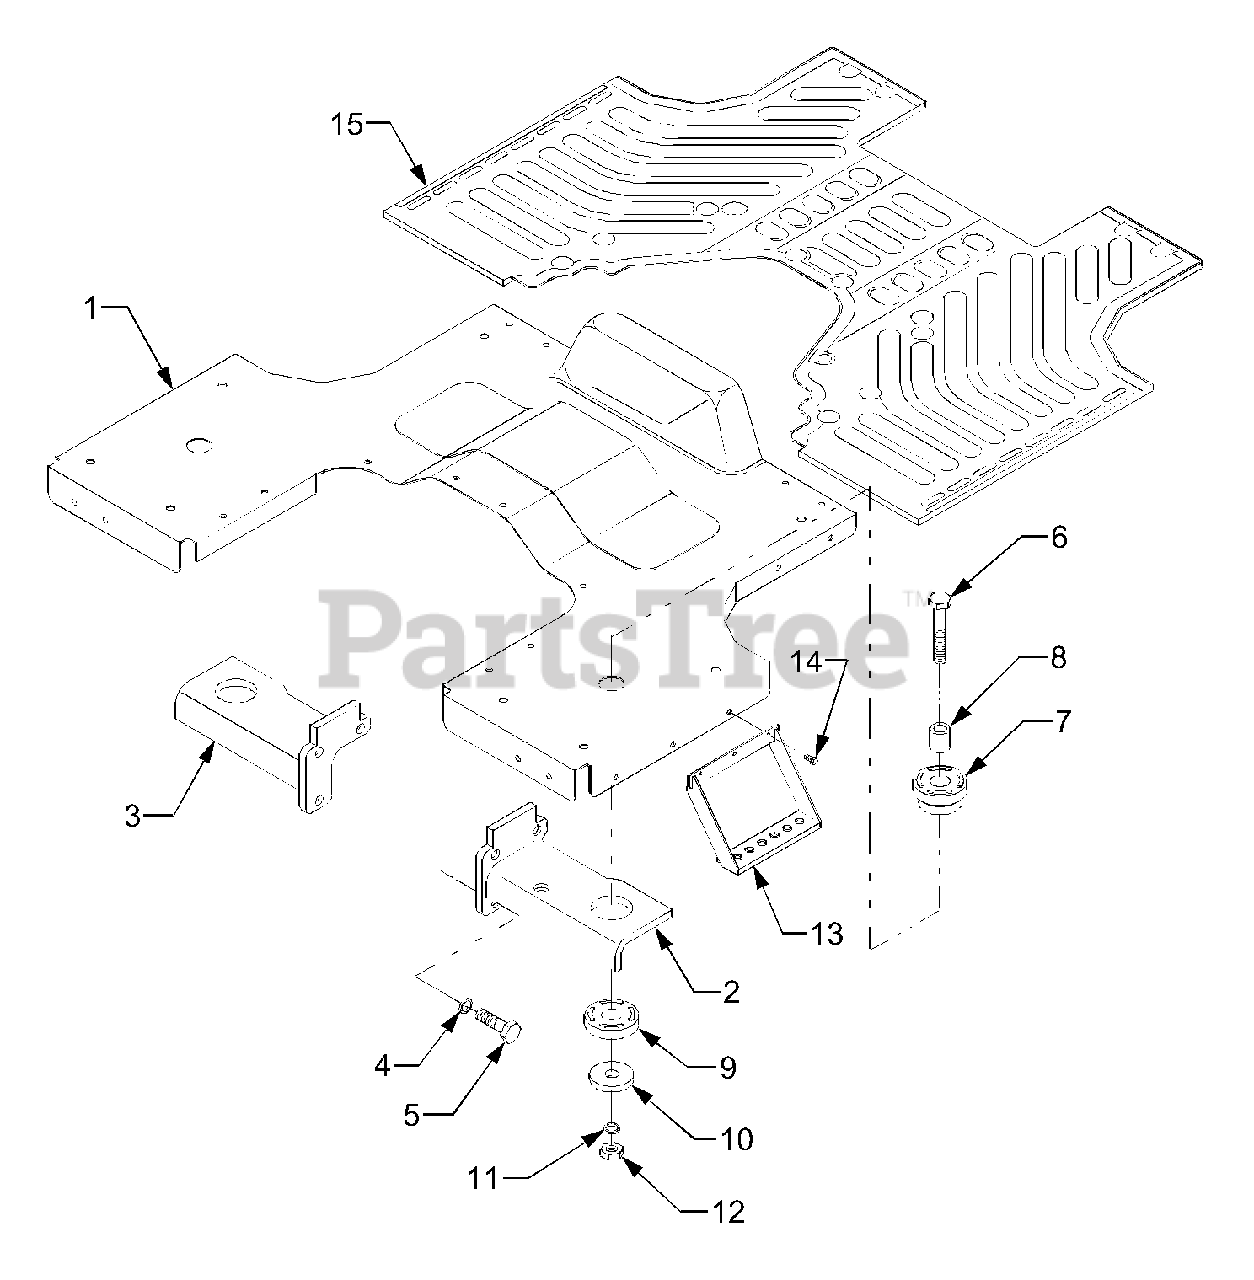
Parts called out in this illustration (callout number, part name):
2	Support, Step (LH)
3	Support, Step (RH)
4	Washer, Spring
7	Rubber, Cabin Cushion (A)
8	Collar, Cabin Cushion (A)
9	Rubber, Cabin Cushion (B)
11	Washer, Spring
13	Step
